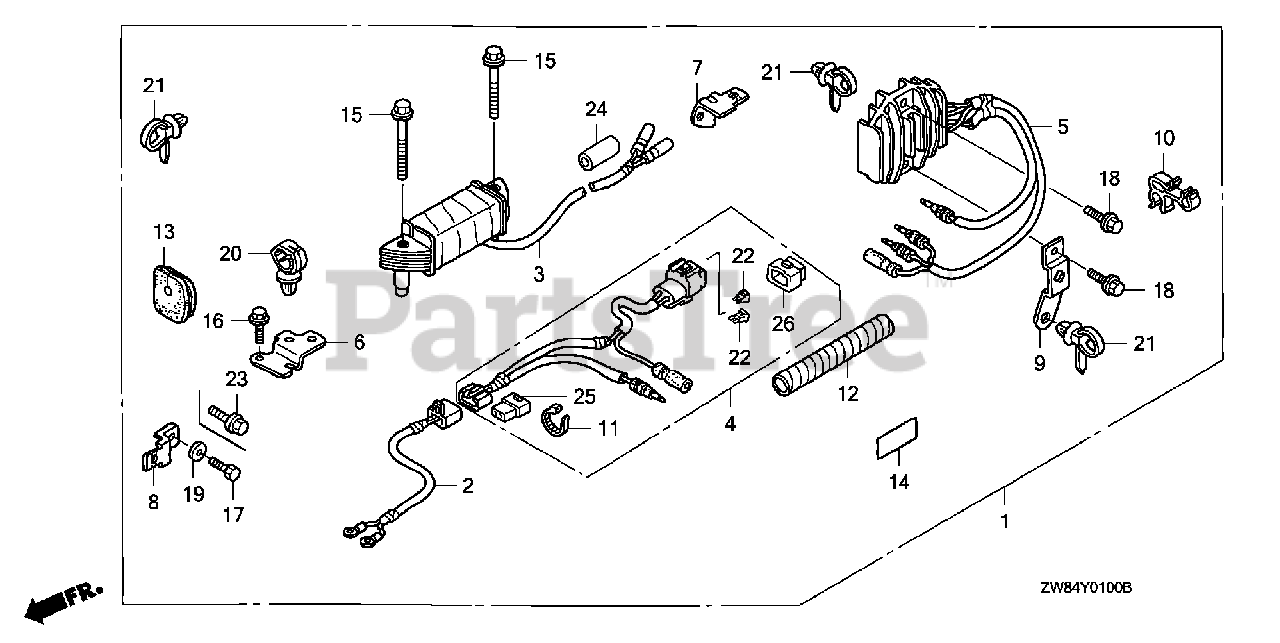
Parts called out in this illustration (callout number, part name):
1	COIL KIT, CHARGE (6A)
2	WIRE ASSY., BATTERY CHARGE
3	COIL ASSY., CHARGE (6A)
4	RECEPTACLE ASSY., CHARGE
5	RECTIFIER ASSY., REGULATOR
6	BRACKET, STARTER CABLE
7	BRACKET, FUSE CASE
8	BRACKET, CONNECTOR (D)
9	BRACKET, E-CLIP
10	CLAMP, DISTRIBUTOR WIRE
11	TIE, CABLE
12	TUBE, SPIRAL A
13	GROMMET B, OIL CASE
14	MARK, RECEPTACLE (6A)
15	BOLT, FLANGE (6X52) (CT200)
16	BOLT, FLANGE (6X14) (CT200)
17	BOLT, HEX. (6X12) Use up to Frame SN 1005248.
18	BOLT, FLANGE (6X26) (CT200)
19	WASHER, PLAIN (6MM) Use up to Frame SN 1005248.
20	CLIP, HARNESS
21	CLIP, HARNESS BAND (151.5MM)
22	FUSE, BLADE (20A)
23	BOLT, FLANGE (6X12) Use from Frame SN 1005249.
24	TUBE, RUBBER (12X14)
25	CONNECTOR, DUMMY
26	COVER ASSY., FUSE (20A)
